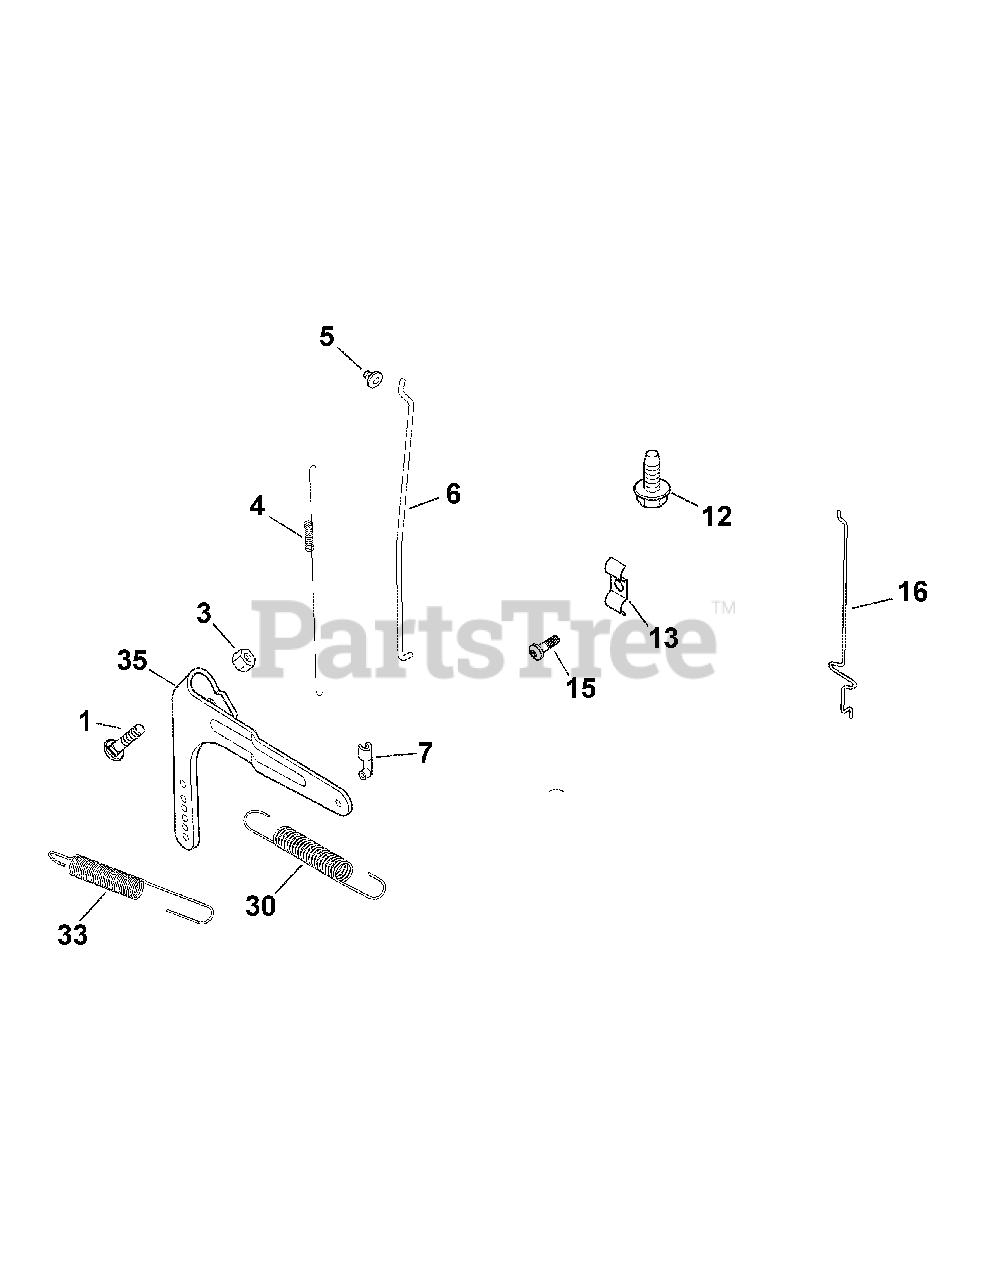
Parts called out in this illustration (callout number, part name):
1	Rd. Hd. Sq. Neck Bolt, M6 x 1.0 x 25
3	Flg. Nut, M6 x 1.0
4	Linkage Spring
5	Linkage Retaining Bushing
6	Throttle Linkage
7	Throttle Linkage Bushing
12	Flg. Thd. Frm. Screw, M6 x 1.0 x 16
13	Dual Conduit Clamp
15	Lbd. Thd. Frm. Screw, M5 x 0.8 x 16
16	Choke Linkage
30	Governor Spring
33	Governor Spring
35	Governor Lever
